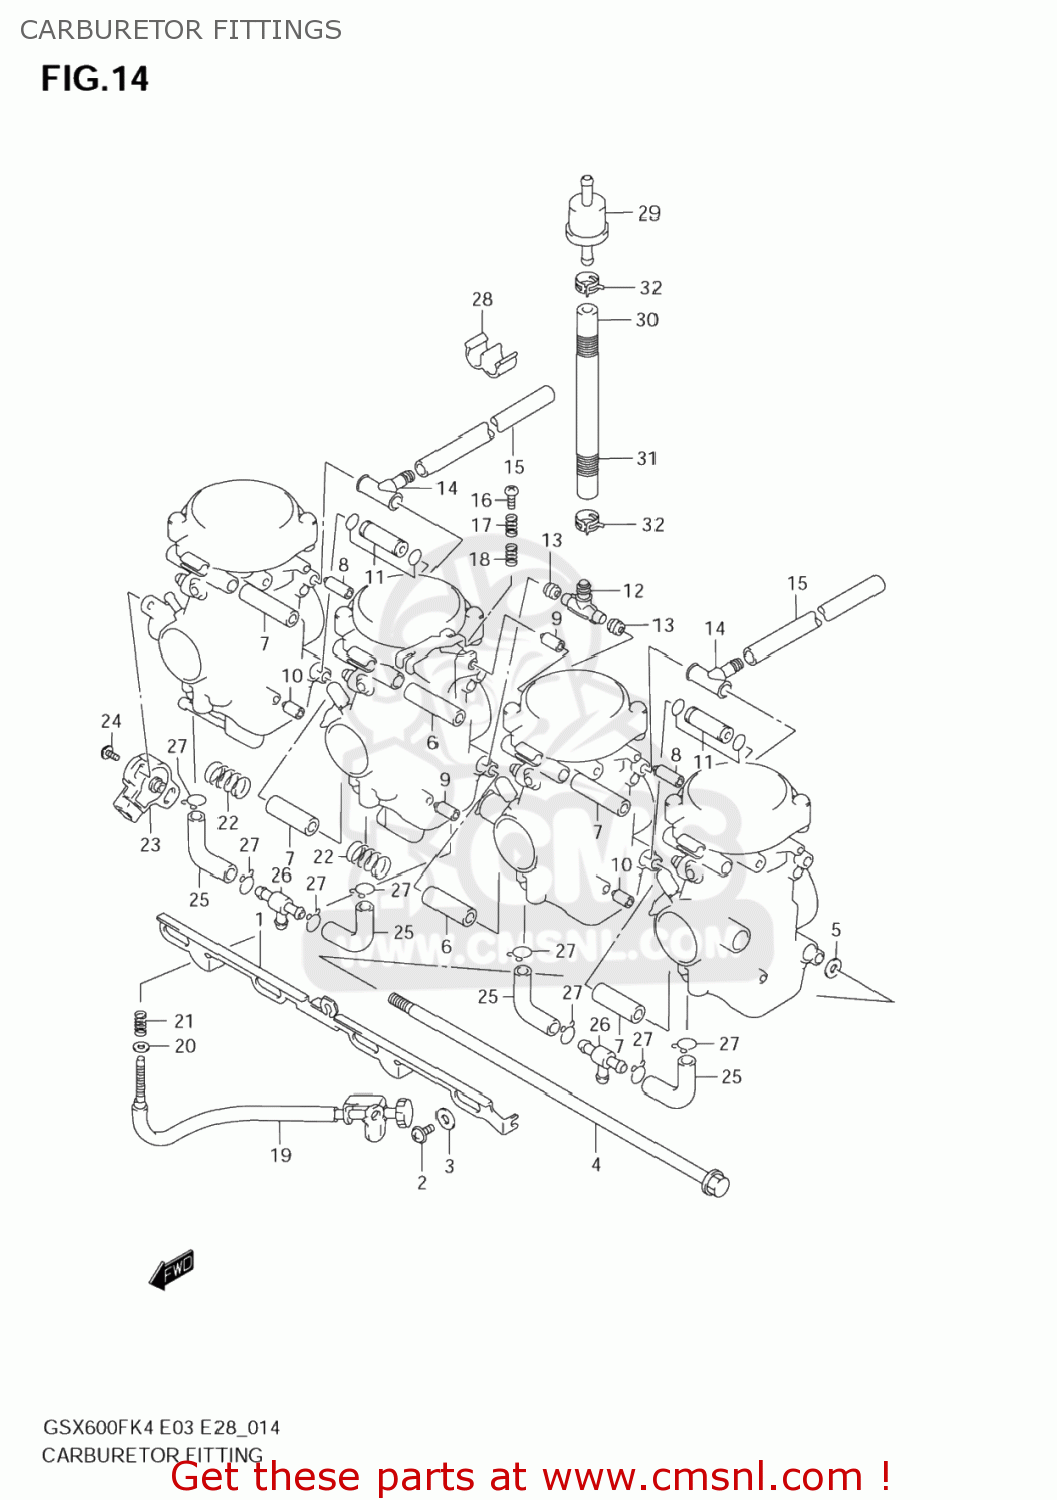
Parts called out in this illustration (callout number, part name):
1	LEVER
2	SCREW
3	PACKING
4	BOLT
5	WASHER
6	PIPE
7	PIPE
8	ROD
9	ROD
10	ROD
11	NIPPLE,CARBURETOR
12	NIPPLE
13	SEAL
14	HOSE
15	HOSE(7X10.2X475)
16	SCREW
17	SPRING
18	SPRING,THROTTLE SCREW
19	SCREW,ADJUST
20	WASHER,STARTER SHAFT
21	SPRING
22	SPRING
23	SENSOR ASSY,THROTTLE
24	SCREW,SENSOR
25	HOSE
26	NIPPLE
27	CLIP
28	CLIP
29	STRAINER,FUEL
30	HOSE(7X12X600)
31	SPRING
32	CLIP
